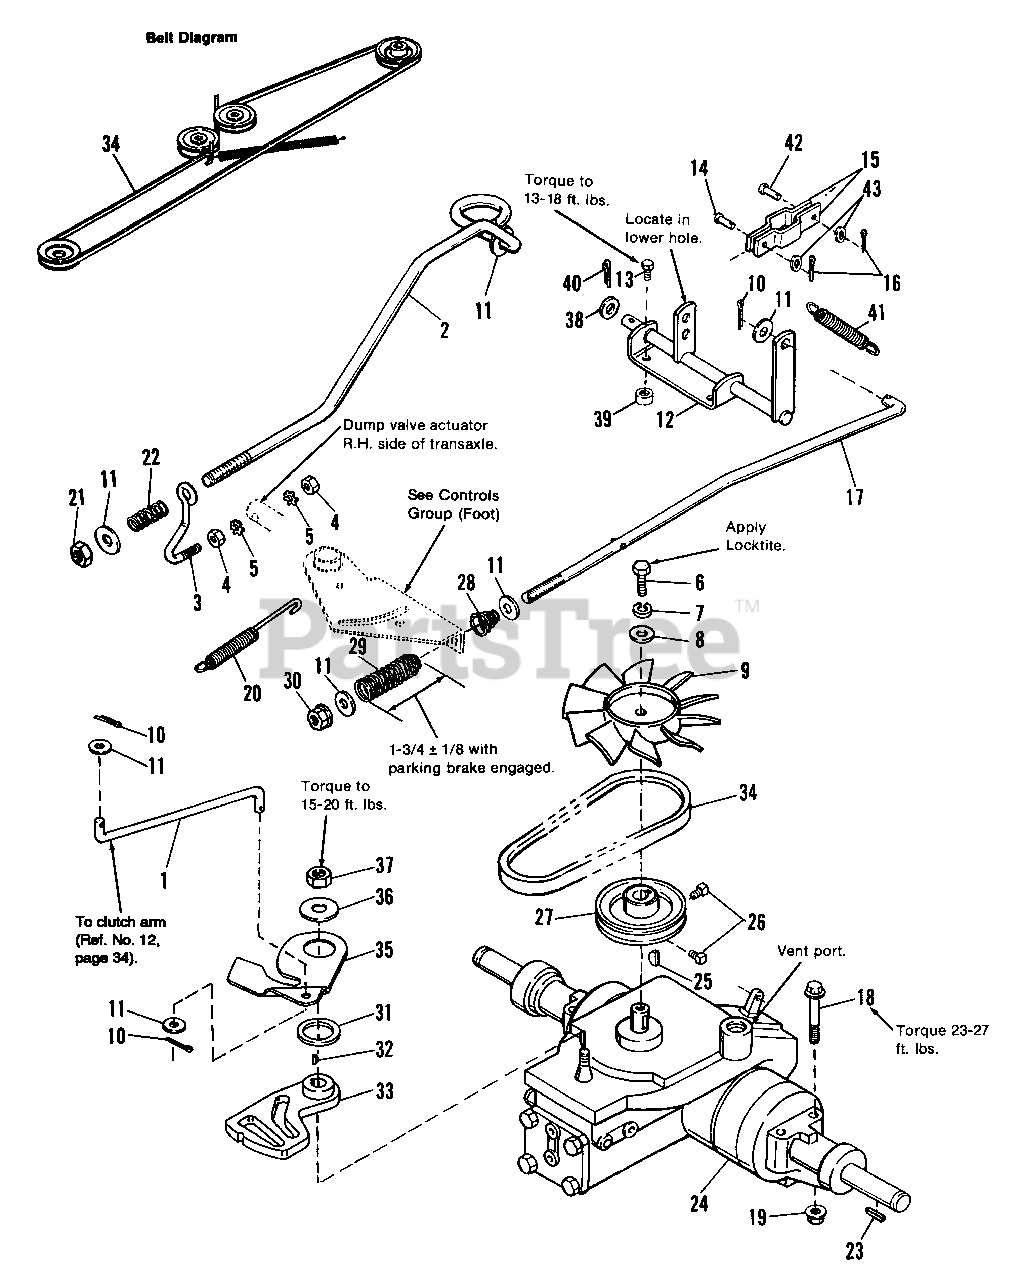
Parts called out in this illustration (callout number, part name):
1	ROD, Neutral Return
2	ROD, Control Valve
3	ROD, Hydro Push Valve
4	NUT, Hex, Full, 1/4-20
5	LOCKWASHER, Ext. Tooth
6	CAPSCREW, 1/4-20 x 1-1/4
7	LOCKWASHER, 1/4
8	WASHER, 1/4
9	FAN, 10 Blade
10	COTTER PIN
11	WASHER, Plain, 13/32
12	BRACKET ASSY., Brake Lever
13	CAPSCREW, 5/16-18 x 1-1/2
14	PIN, Clevis
15	CLEVIS BARS
16	COTTER PIN
17	ROD, Brake
18	CAPSCREW, 3/8-16 x 3
19	NUT, Hex, Flange Lock, 3/8-16
21	NUT, Hex, Centerlock, 1/4-20
23	KEY, 1/4 x 2-1/4
24	* HYDROSTATIC TRANSAXLE
25	KEY, Hi Pro
26	SETSCREW, Sq. Hd., 1/4-28
27	PULLEY, Driven
28	SPRING, Conical
30	NUT, Flange Lock, Nylon, 5/16-18
31	SPACER, Cam
32	KEY, Woodruff, 1/8 x 1/2
33	CAM, Hydro
34	BELT, Drive
35	CAM, Neutral Return
37	NUT, Hex Lock, 3/8-16
38	WASHER
40	COTTER PIN
41	SPRING, Extension
42	PIN, Clevis
43	WASHER
